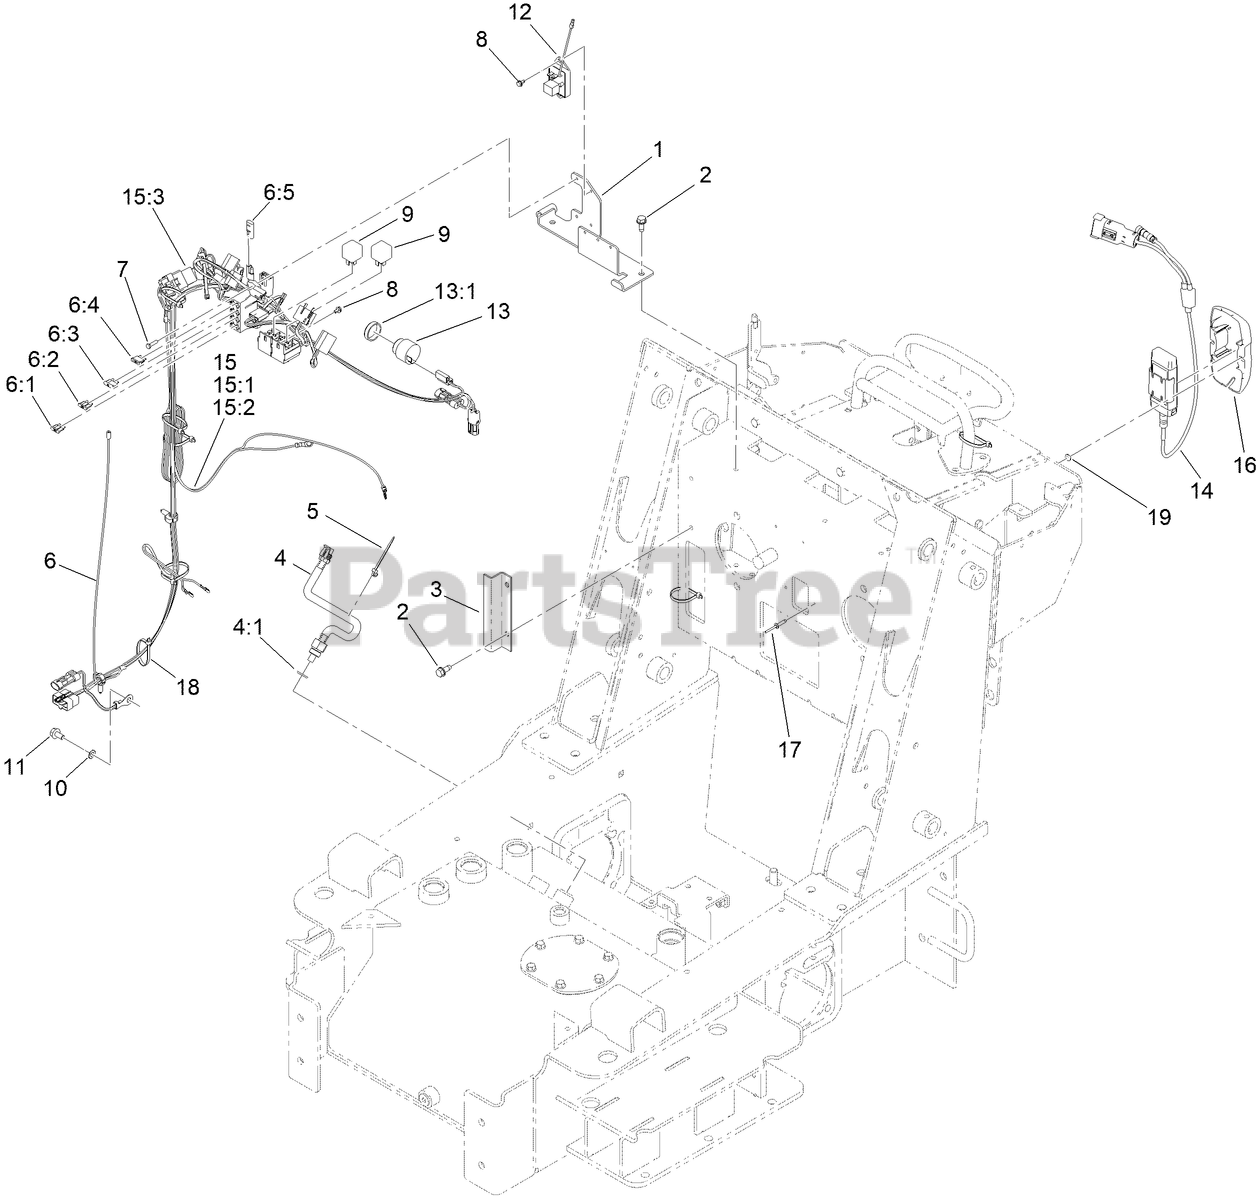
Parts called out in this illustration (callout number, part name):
1	BRACKET-FUSE/RELAY
2	SCREW-THD ROLL, HWH
3	SHIELD-WIRING
4	SWITCH-TEMPERATURE
4:1	O-RING
5	TIE-CABLE
6	HARNESS-WIRE
6:1	FUSE-BLADE, 30 AMP
6:2	FUSE-BLADE, 25 AMP
6:3	FUSE-BLADE, 10 AMP
6:4	FUSE-BLADE, 15 AMP
6:5	CAP-PLUG
7	SCREW
8	SCREW-HWH
9	RELAY
10	WASHER-LOCK
11	SCREW-HHF
12	MODULE-IGNITION DELAY
13	AUDIO ALARM ASM
13:1	NUT-PLASTIC, KNURLED
15	HARNESS-WIRE, GPS
15:1	FUSE-MINI BLADE, 3 AMP
15:2	COVER-FUSE, SINGLE
15:3	RELAY-MINI
16	COVER, GPS
17	RIVET-POP
18	TIE-CABLE
19	WASHER-PLAIN
